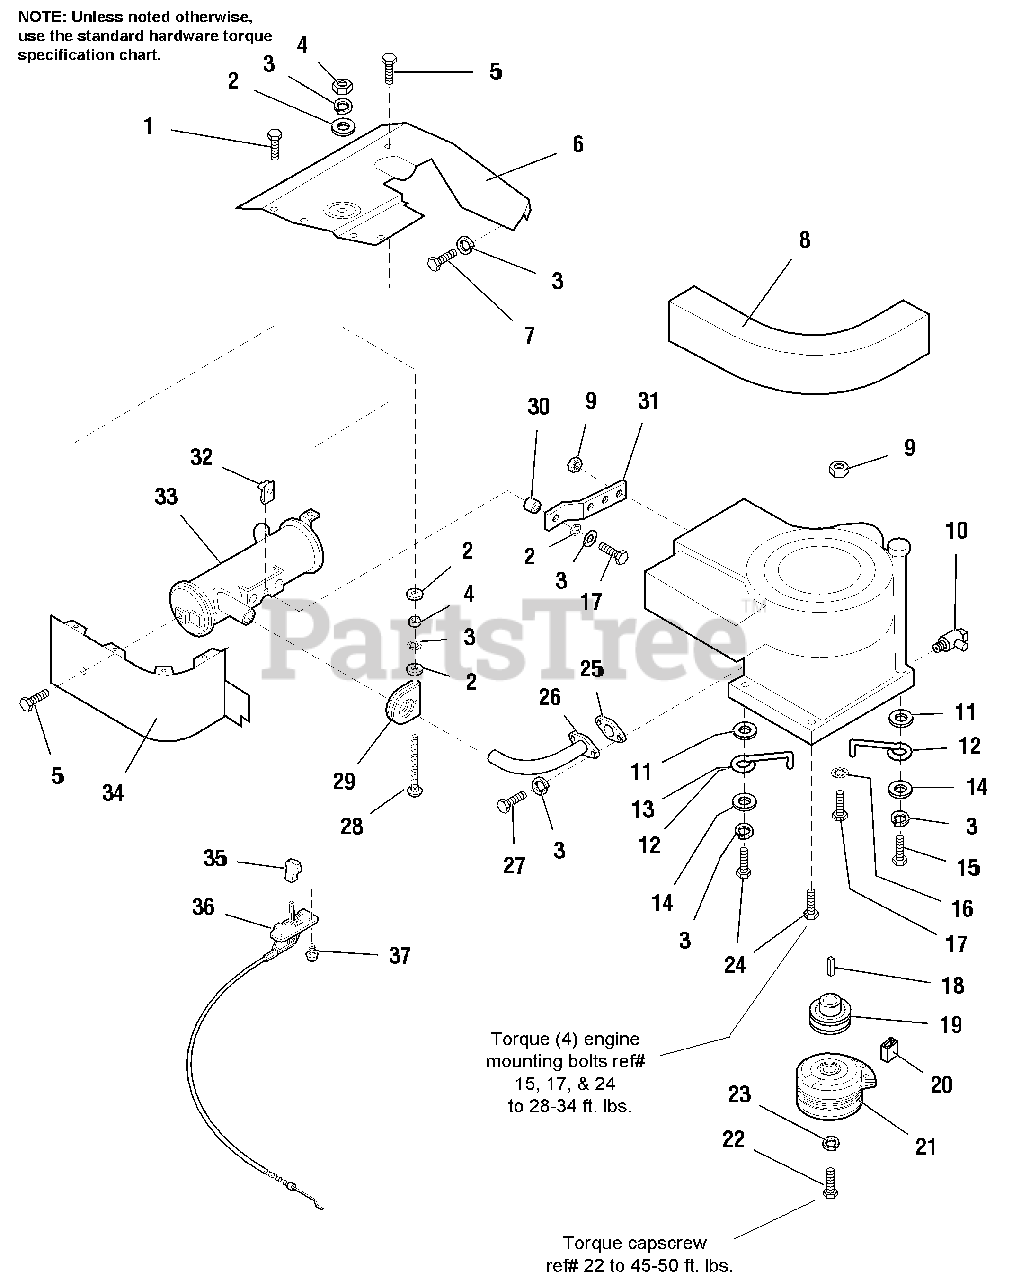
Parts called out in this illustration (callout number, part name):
1	SCREW, Self-Tapping, #10-16 x 3/8
2	WASHER, .34
3	LOCKWASHER, 5/16
4	NUT, Hex, 5/16-18
5	SCREW, Hex, Taptite, 5/16-18 x 1/2
6	DUCT, R.H., Top
7	CAPSCREW, 5/16-18 x 3/4
8	SEAL, Air Inlet
9	NUT, Flange, Whiz-Lock, 5/16-18
10	VALVE, Shut-Off
11	WASHER, Plain
12	BELT STOP
12	BELT STOP, Rear
13	BELT STOP, Front
14	WASHER, Plain, 3/8
15	SCREW, Taptite, 3/8-16 x 2
16	NUT, Speed, 5/16-18
17	SCREW, Hex, Whiz-Lock, Flange, 5/16-18 x 1-1/2
18	KEY, Hi-Pro
19	PULLEY, Engine
20	SLEEVE, Clutch Anchor
21	CLUTCH, Electric
22	CAPSCREW, 7/16-20 x 2-1/2
23	LOCKWASHER, 7/16
24	SCREW, Taptite, 3/8-16 x 1-1/2
25	GASKET, Muffler
26	PIPE, Exhaust
27	SCREW, Socket Hd., 5/16-18 x 3/4
28	CARRIAGE BOLT, 5/16-18 x 3-1/4
29	CLAMP, Muffler
31	SUPPORT, Muffler
32	SPEED NUT, 5/16-18
33	MUFFLER ASSY.
34	DUCT, L.H.
35	KNOB, Throttle
36	THROTTLE CONTROL ASSY.
37	SCREW, Plastite, 1/4-10 x 1/2
